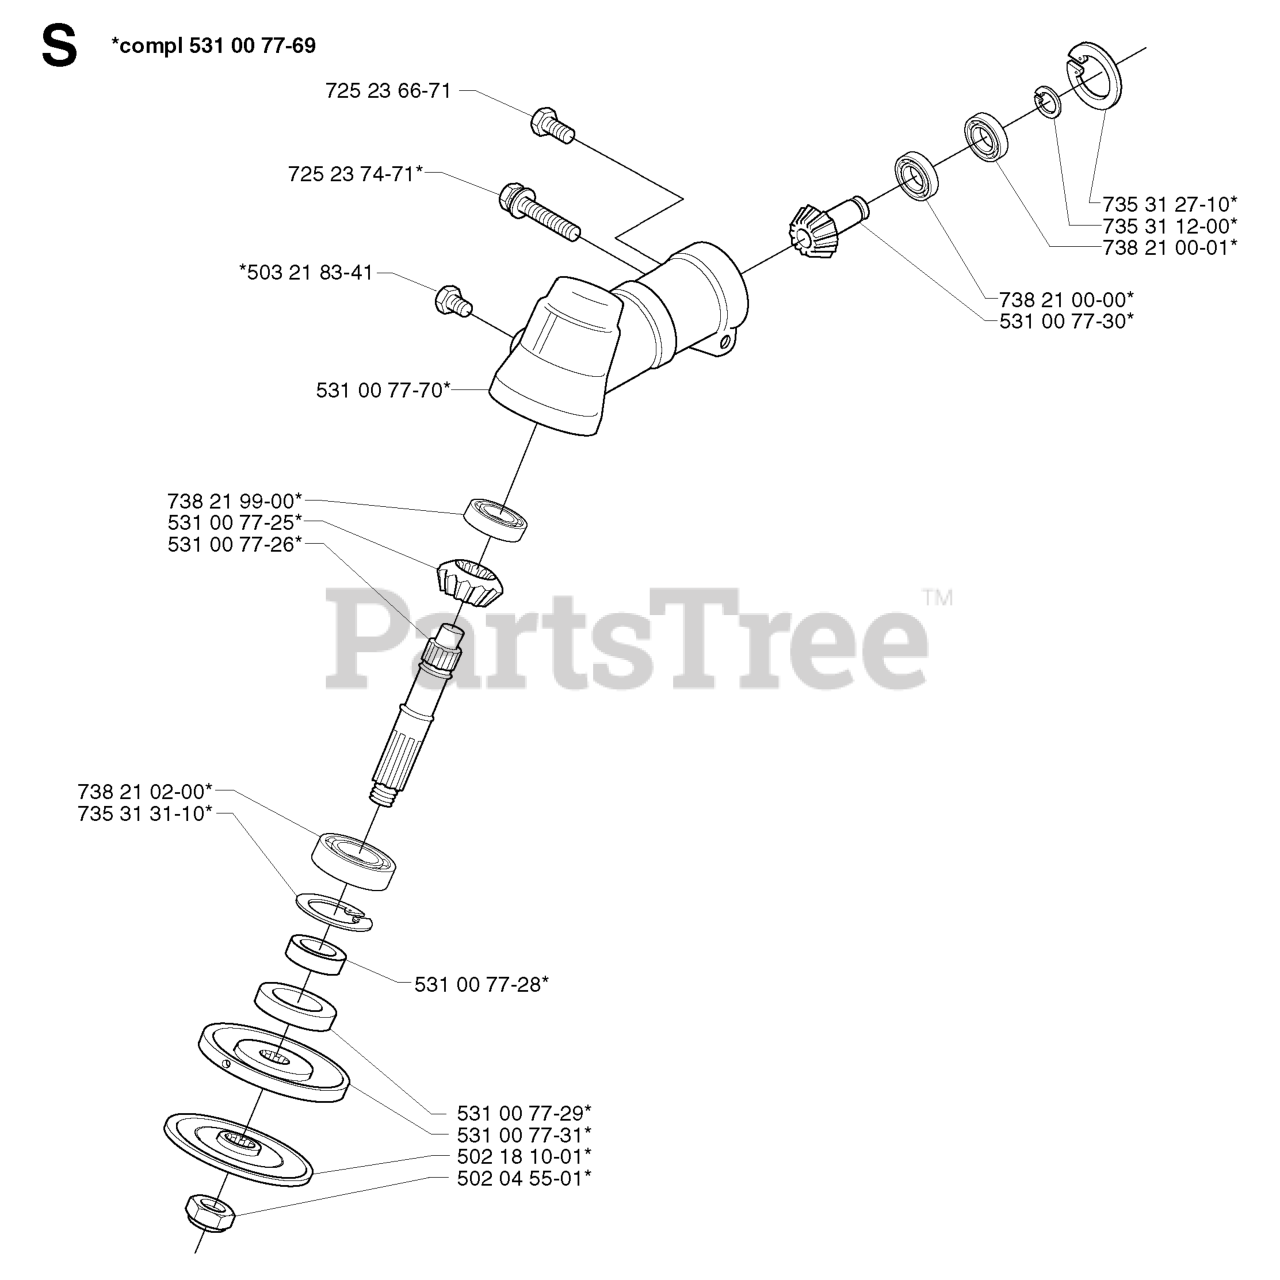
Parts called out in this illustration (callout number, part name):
2	DRAWBAR.STGT
3	RP LOGO
14	HOOD
15	LENS.LH.TEX.GT.HUSQ.CL
18	GRILL.ASM.HUSQ.TG/CRD.W/TRIM
25	LENS.RH.TEX.GT.HUSQ.CL
36	SCREW 5/16"
37	FENDER.PNT.TX.GT.CH/FW.ORANGE
58	BRKT.SUPPORT.FNDR/TANK
68	Screw 5/16-18 x 1/2 Hex, Self Tapping 5/16-18 x 1/2
130	SCREW.#10 X 0.750.BOS
137	BUMPER DASH
150	AIR.DUCT.HOOD.TEX.GT.HUSQ
152	SHIELD.BROWNING/DEBRIS
159	SCREW, 3/8-16X3/4
161	CONSOLE.FUEL.WINDOW.HU
162	SCREW.HI-LO.CONSOLE
165	SUPPORT.TANK.REAR.B/TE
175	PLATE.CROSSMEMBER.HUSQ
176	SCREW.#10-24X5/8.RN.QU
177	BUSHING, STEERING
178	CARGO.ASM.NET.TXGT.W/C
180	CHASSIS.STAMPING.LT/GT
181	BUSHING.MNT.FEND.CRGO.
182	DASH.LOWER.COMMON.12V.ADAPTOR
183	BOLT.5/16-18X1-1/4 FULL THD
189	SCREW
194	NUT LOCK HEX FLANGE 5/16-18
195	PLUG.HOLE.DASH.LOWER.12V.BLK
196	CONSOLE.ASM.DCKLFT.W/RF.HQ.DLR
199	PLATE.DECK.LIFT.HUSQVARNA.GT
202	VENT.SIDE.HOOD.HUSQ.RH.GREY
203	VENT.SIDE.HOOD.HUSQ.LH.GRAY
204	HOOD VENT
205	SKIRT.HOOD.SIDE.HUSQ.RH.GREY
206	SKIRT.HOOD.SIDE.HUSQ.LH.GREY
207	BEZEL.RH.TEX.GT.HUSQ
208	BEZEL.LH.TEX.GT.HUSQ
209	INSERT.HEX.GRILL.HUSQ.GREY
210	INSERT.HEX.GRILL.HUSQ.
211	INSERT.HEX.GRILL.HUSQ.
212	INSERT.HEX.GRILL.HUSQ.
214	CLIP.RETAINER.TINNER.
217	ROD.PIVOT.HOOD
221	REFLECTOR.LH.TEX GT HU
228	STUD.FASTNER.W/ANTI-ROTATE
234	BUMPER.HOOD.TEX.HUSQVARNA
235	SPACER FENDER
236	NUT.CENTERLOCK.5/16-
238	TRIM.HUSQ.TG/CRD.SERVICE
298	NUT PUSH M
